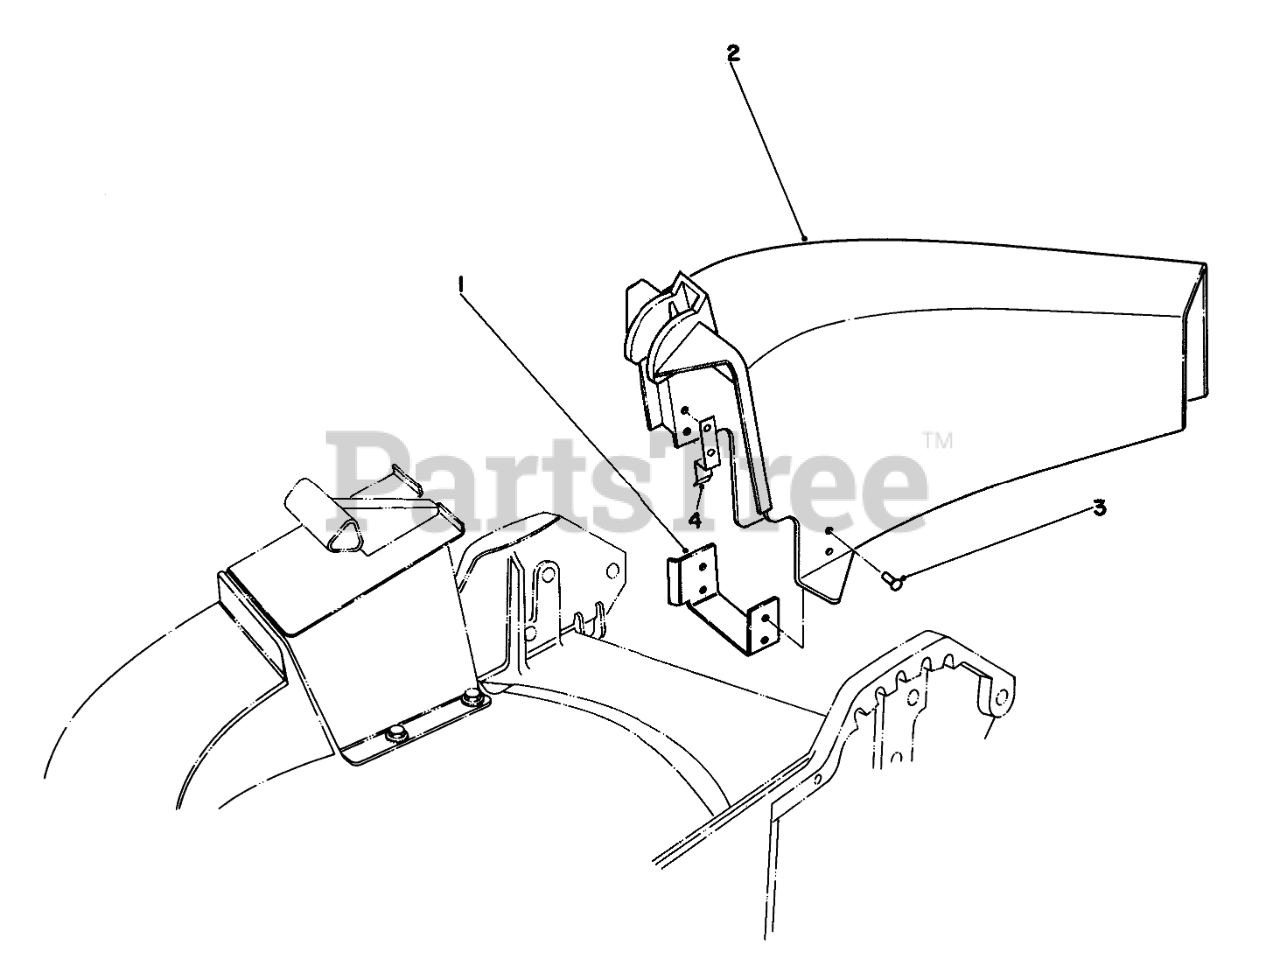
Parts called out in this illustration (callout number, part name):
1	CHUTE BRACKET
2	Chute Discharae
3	RIVET
4	CHUTE TAB
